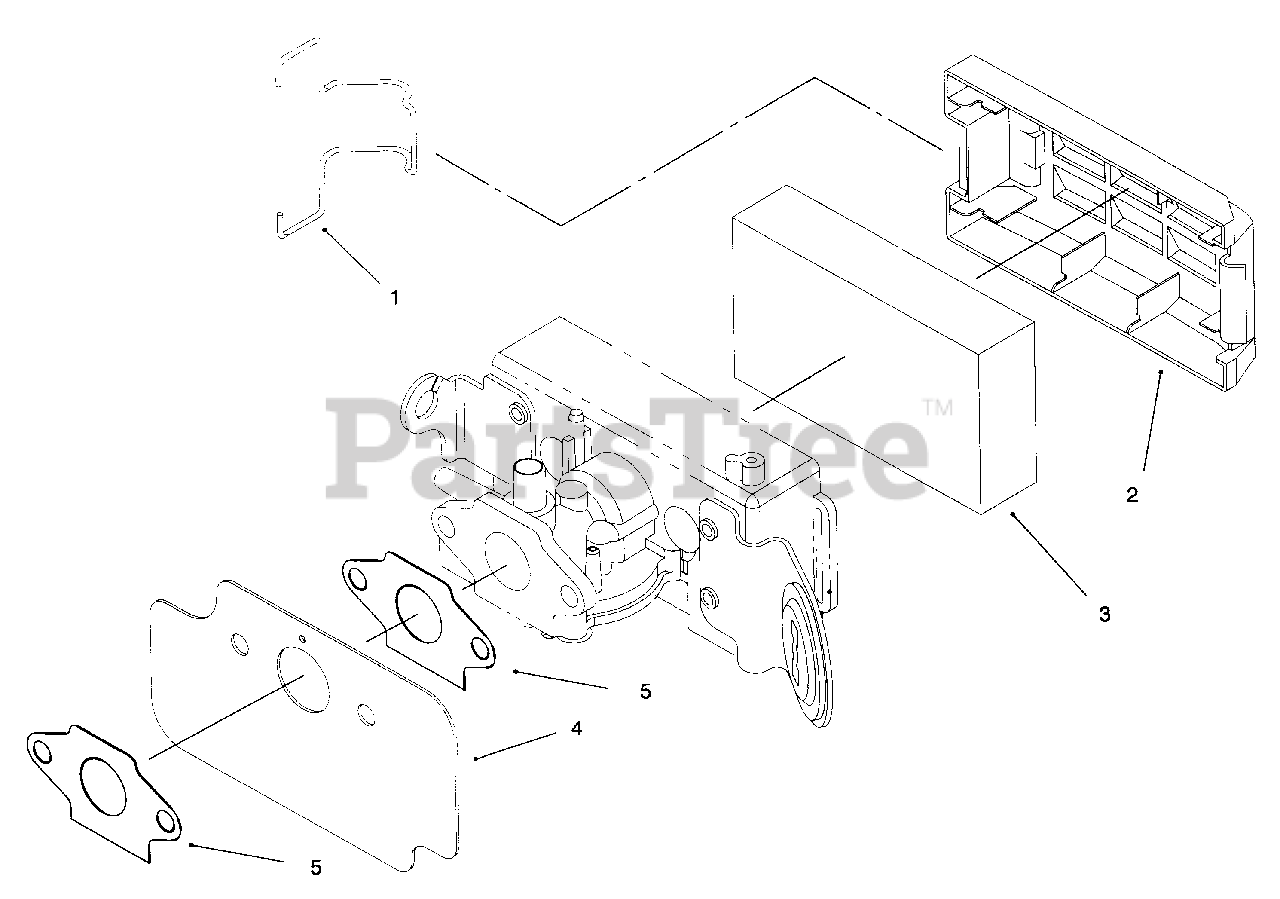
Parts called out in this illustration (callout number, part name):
1	Retainer-Cover
2	Cover-Air Filter
3	Element-Air Filter
4	Shield-Heat
5	Gasket-Carb.
